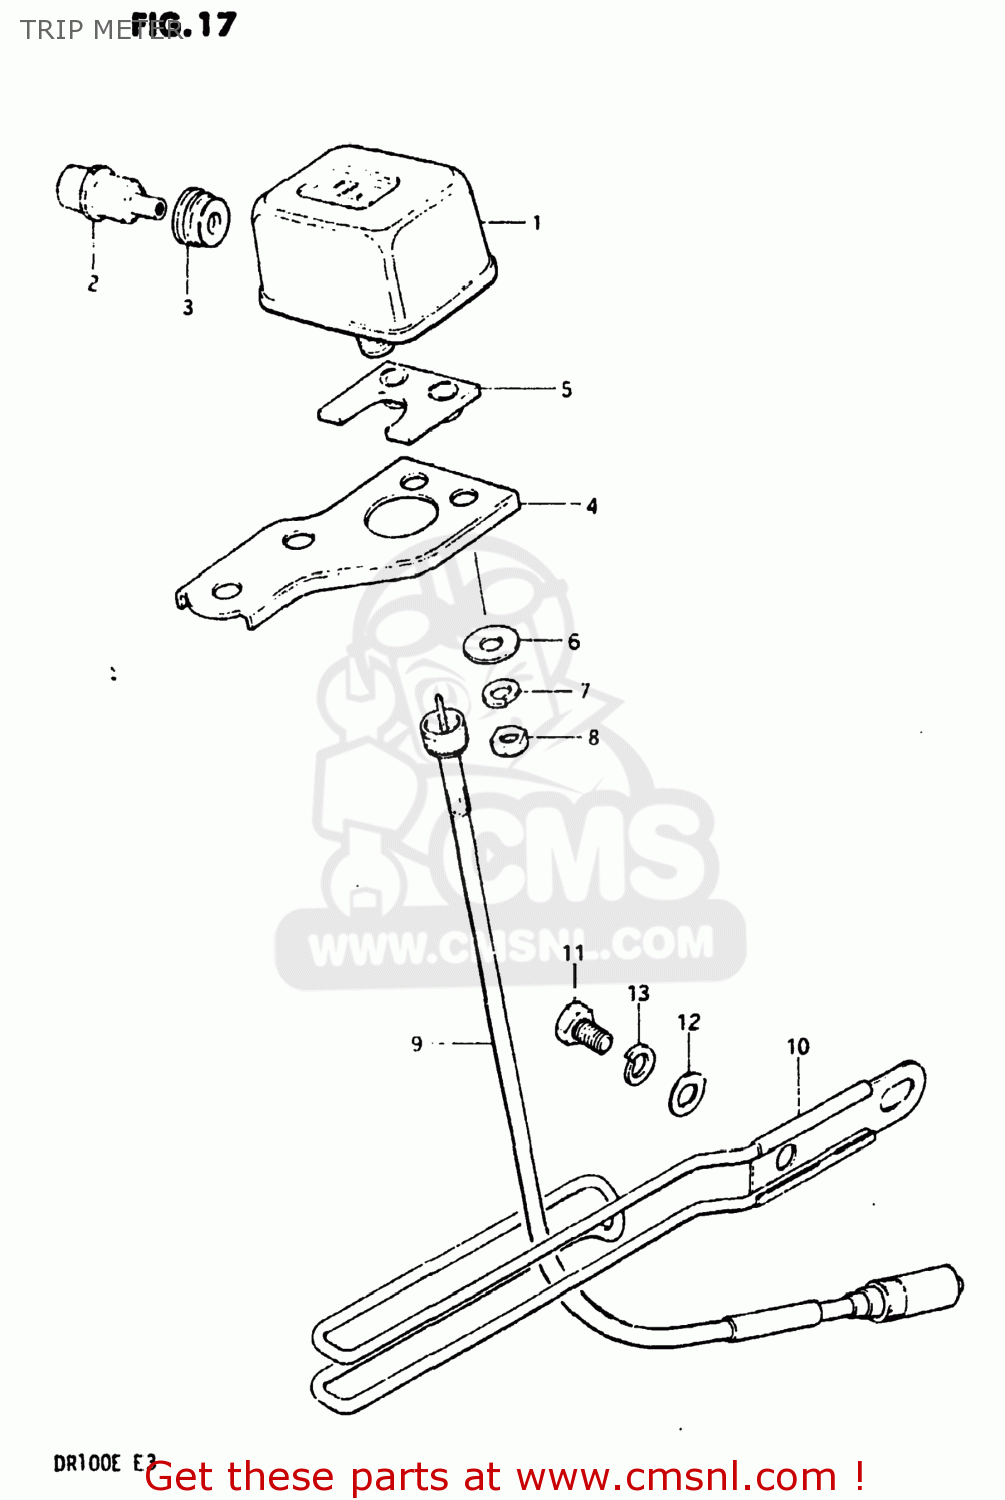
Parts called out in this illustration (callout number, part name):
1	TRIP METER
2	KNOB,TRIP METER
3	COVER,TRIPMETER KNOB
4	BRACKET,TRIPMETER
5	CUSHION,TRIPMETER
6	WASHER,METER
7	LOCK WASHER
8	NUT
9	CABLE ASSEMBLY,SPEEDOMETER
10	GUIDE,CABLE
11	BOLT 8X12
12	WASHER
13	LOCK WASHER
